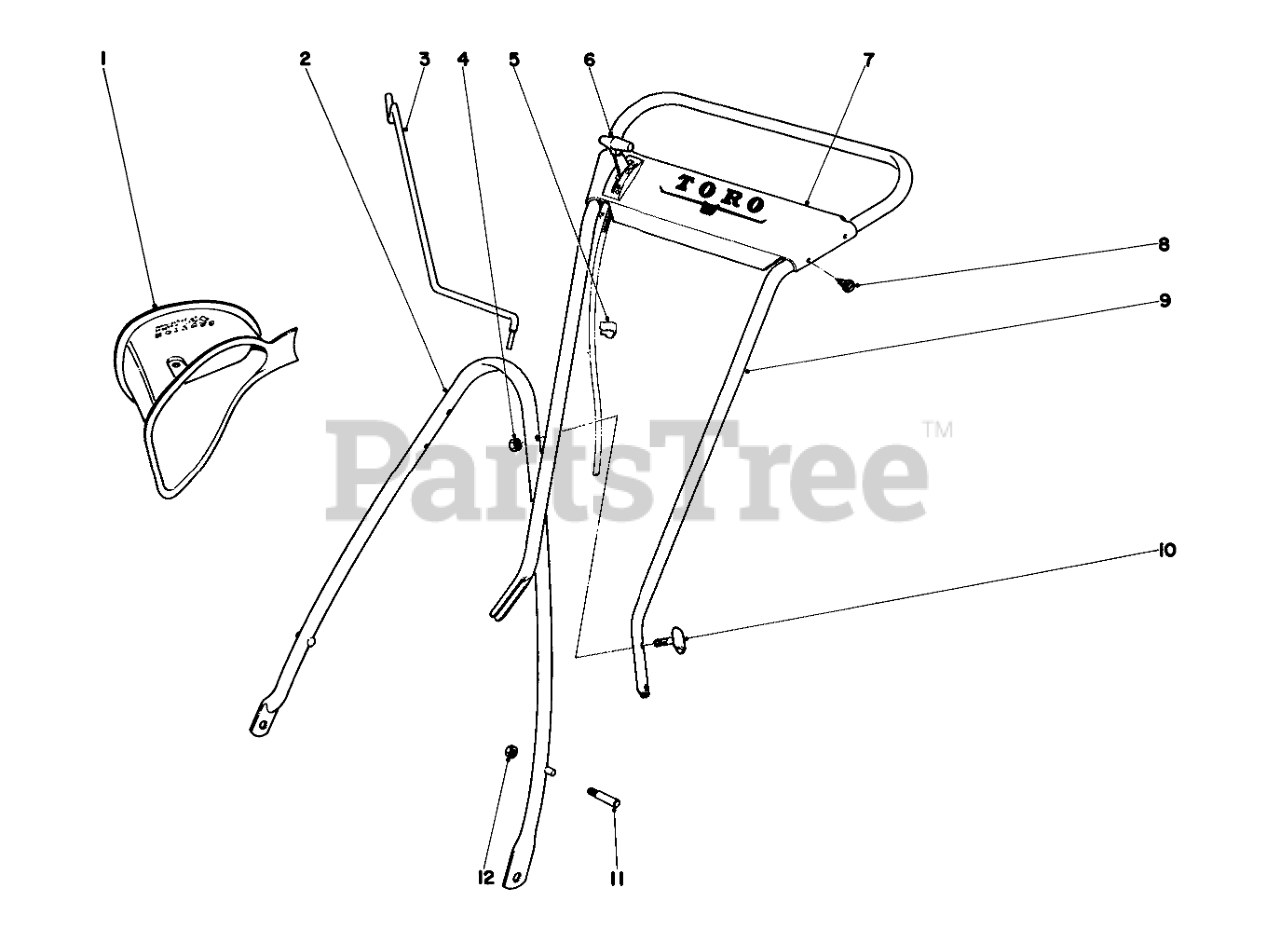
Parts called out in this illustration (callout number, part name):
1	BAG ATTACHMENT
2	Handle-Lower
3	GRASS BAG HANGER
4	Nut
5	CONTROL WIRE CLIP
6	Throttle Control
7	Escutcheon
8	SCREW-HWHTF
9	Handle-Upper
11	Handle Pin
12	Nut
